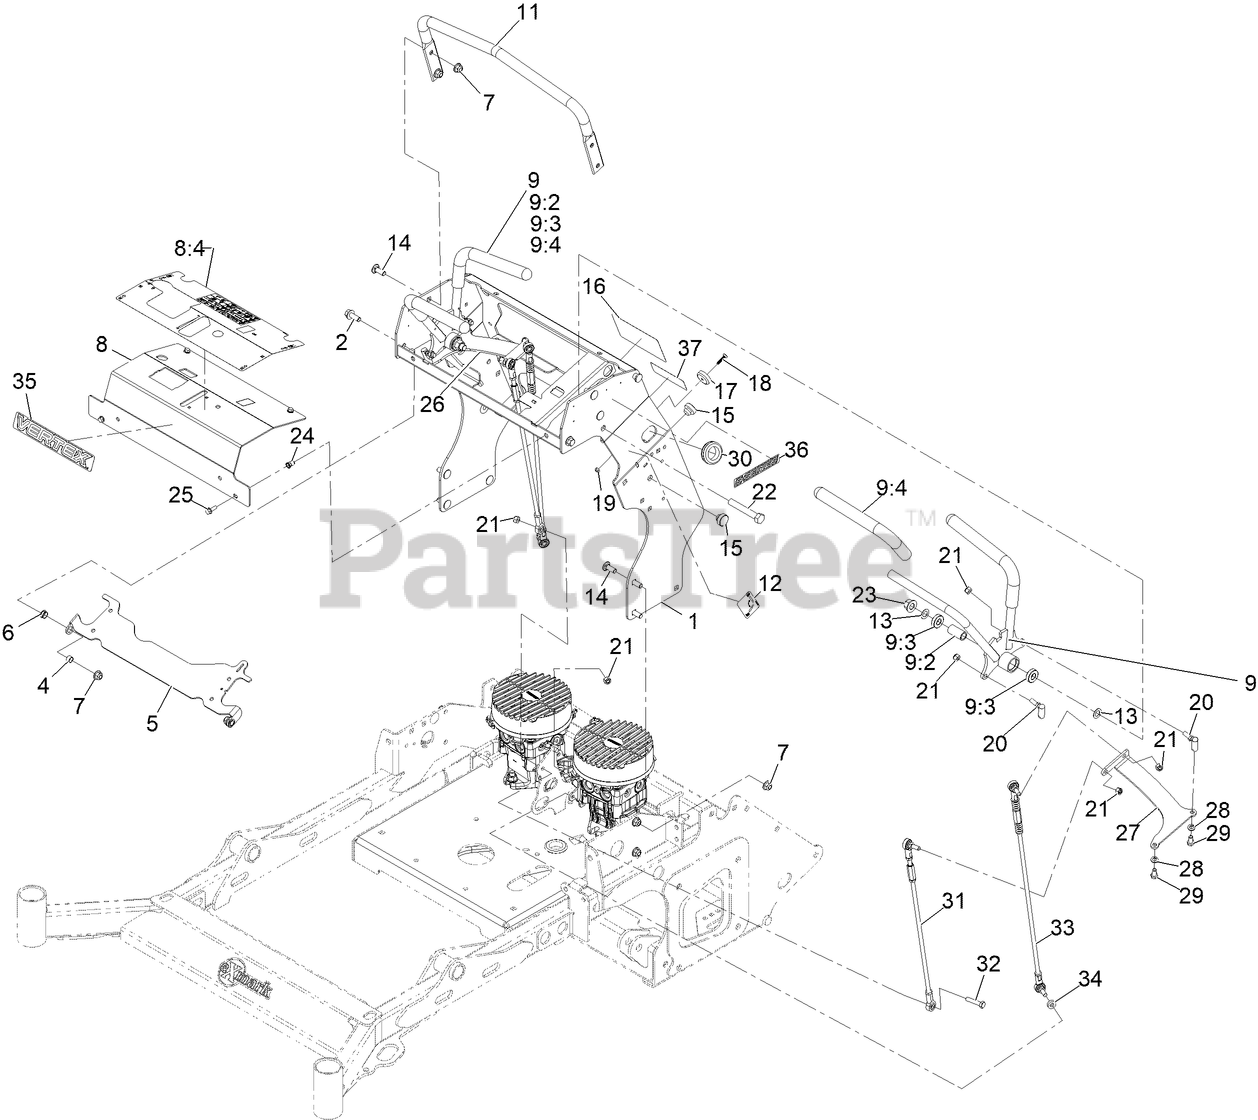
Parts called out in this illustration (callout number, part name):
1	ASM-Tower [red]
2	SCREW-HHF 3/8-16 X 1
4	SPACER-BRAKE PIVOT
5	Spacer-Brake Pivot
6	BUSHING,SNAP
7	NUT-HF, NI
8	PANEL-CONTROL W/ DECAL
8:4	DECAL-CONTROL PANEL NON-EFI
9	ASM-CTRL LEVER
9:3	BEARING-WHEEL
9:4	GRIP-HANDLE, CONTROL
11	BAR-REFERENCE
12	DECAL-PARK BRAKE, CE
14	SCREW-CARR
15	BUMPER-RUBBER
16	DECAL-SERVICE AID
17	MAGNET-RARE EARTH THIGH PAD
18	SCREW FLAT HD #10-24X1.00
19	NUT-LOCK
20	BALLJOINT-RH (W/GROMMET)
21	NUT-LOCK
22	SCREW-HH
23	Nut-Lock 1/2-13
24	Nut-Clinch, Hex
25	SCREW-HHF
26	BRACKET-LINK CTRL LH
27	BRACKET-LINK CTRL RH
28	WASHER-LOCK
29	SCREW-HH
30	GROMMET
31	ASM-MOTION CONTROL SHORT
32	SCREW-HH
33	ASM-MOTION CONTROL LONG
35	DECAL-VERTEX LOGO
36	Decal-S-Series
37	DECAL-FUSE
